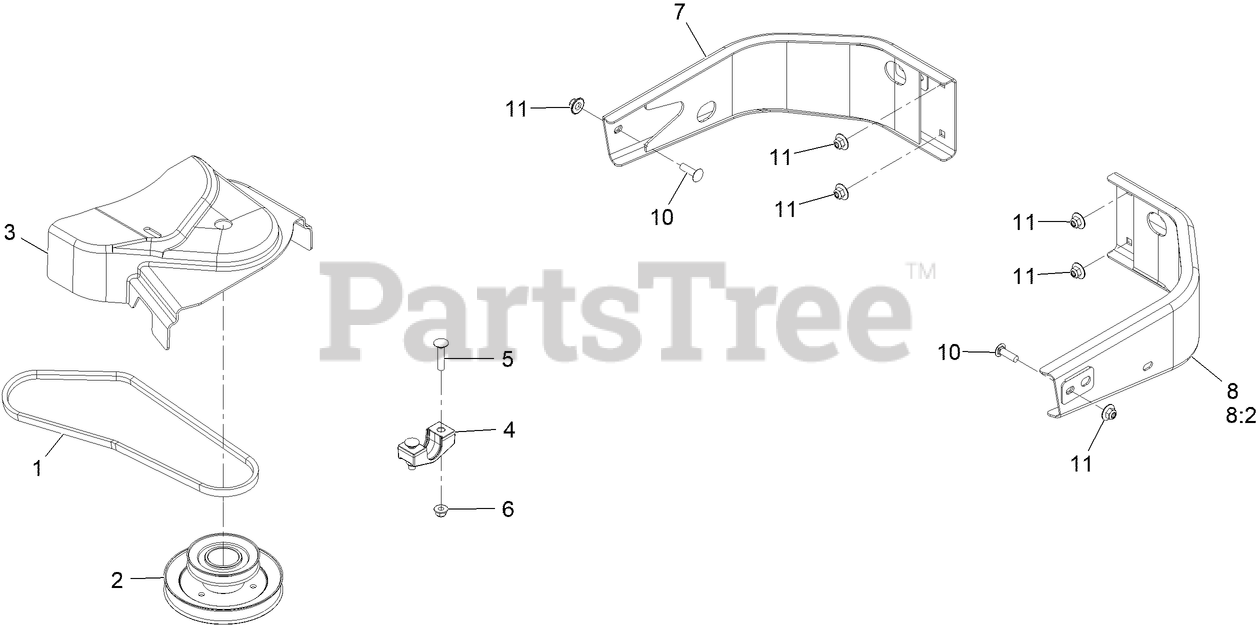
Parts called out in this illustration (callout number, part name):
2	JACKSHAFT,UV DRIVE 524 SPLINED
3	COVER,BELT UV 52
4	SUPPORT-BEARING CROSS SHAFT
5	SCREW-CARR
6	NUT-HF, NI
7	BUMPER-RH
8	LH BUMPER ASM
8:2	DECAL-WARNING
10	Bolt-Carriage 3/8-16 X 1 1/4
11	Nut-Nyloc 3/8-16 Flg
